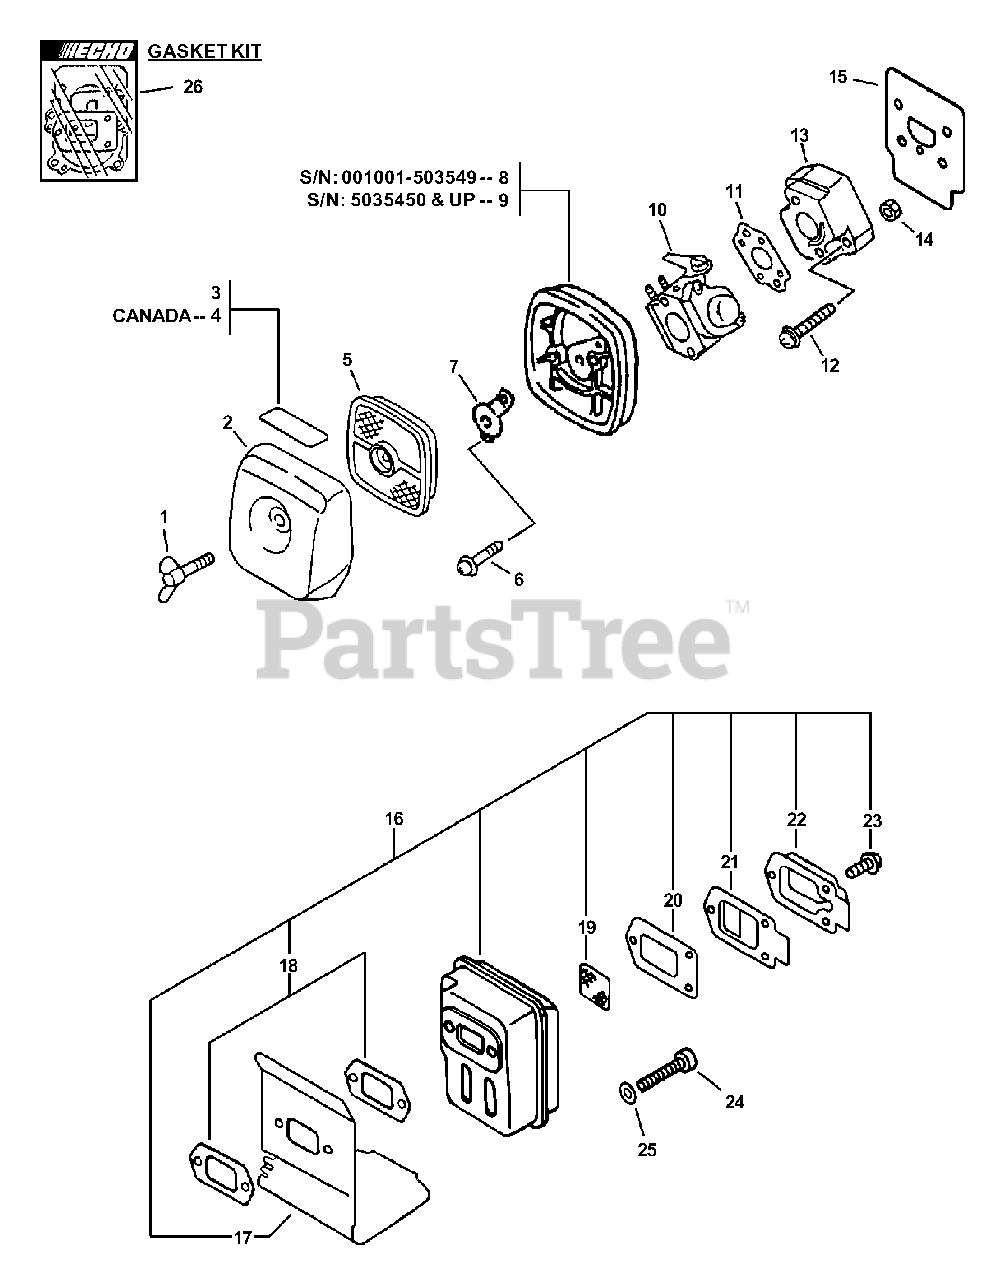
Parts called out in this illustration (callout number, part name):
1	BOLT, WING 5×20
2	COVER, AIR FILTER - BLACK
3	LABEL, CHOKE
4	LABEL, CHOKE
5	FILTER, AIR - SINGLE LAYER
6	SCREW 5×65
7	PLATE, PREVENT
8	CASE ASSY, AIR FILTER
9	CASE ASSY, AIR FILTER
10	CARBURETOR - C1U-K52
11	GASKET, INTAKE
12	SCREW 5×20
13	INSULATOR, INTAKE
14	NUT M5
15	HEAT SHIELD, INTAKE
16	MUFFLER ASSY
17	COVER, EXHAUST
18	GASKET, EXHAUST
19	SCREEN, SPARK ARRESTER
20	GASKET, EXHAUST
21	GUIDE, EXHAUST
22	GUIDE, EXHAUST - INNER
23	SCREW 4×10
24	BOLT 5×55
25	WASHER, FLAT 5.5×10×0.8
26	GASKET KIT
